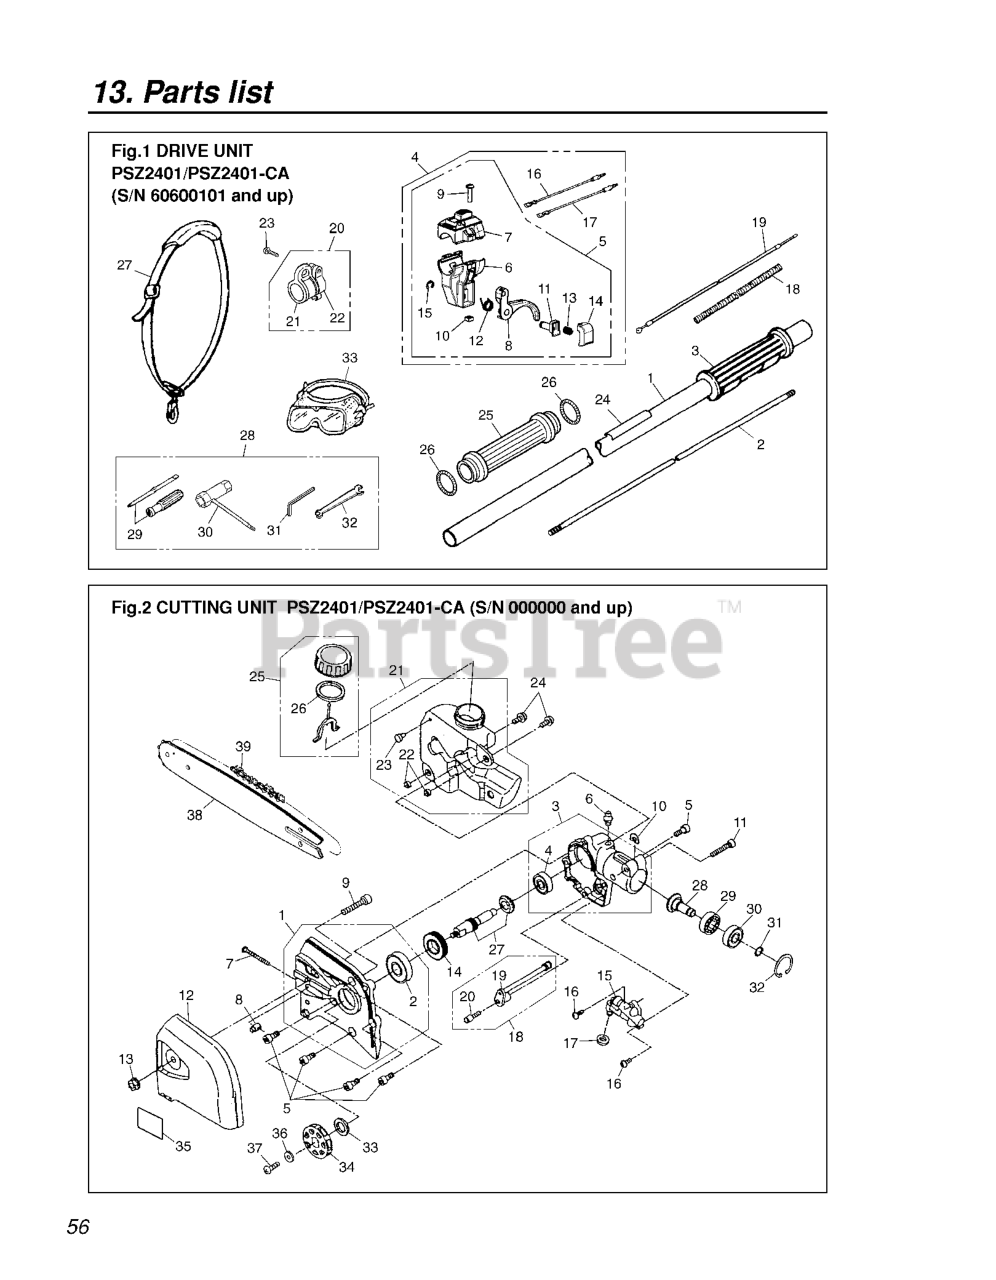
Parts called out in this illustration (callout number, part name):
1	PIPE COMP
4	LEVER COMP (RPLS 8488R20343)
5	LEVER (FLEX. LEVER)(RPLS -13)
7	COVER COMP (RPLS 611014410-02)
8	THROTTLE TRIGGER
16	CORD (A), BLACK
17	CORD (B), RED
20	HANGER COMP.
21	HANGER
27	HARNESS-ASSY***
28	TOOL-SET
33	GOGGLExxx (RPLS
A1	CASE L-COMP
A3	GEARCASE COMP (RIGHT)
A5	BOLT, M5 x 12
A9	BOLT, M6 x 30
A12	COVER, CHAIN
A14	GEAR, WORM
A15	PUMP ASSY, OIL
A18	PIPE ASSY, OIL
A19	PIPE, OIL
A21	TANK ASSY,OIL(RPLS T307313800)
A24	SCREW, M5 x 12
A25	CAP ASSY, OIL
A26	GASKET, OIL CAP
A27	SHAFT, GEAR
A28	GEAR, BEVEL
A34	SPROCKET
A35	LABEL (PSZ2500)
A38	USE PSZ12
A39	Saw Chain, 12" Polesaw
